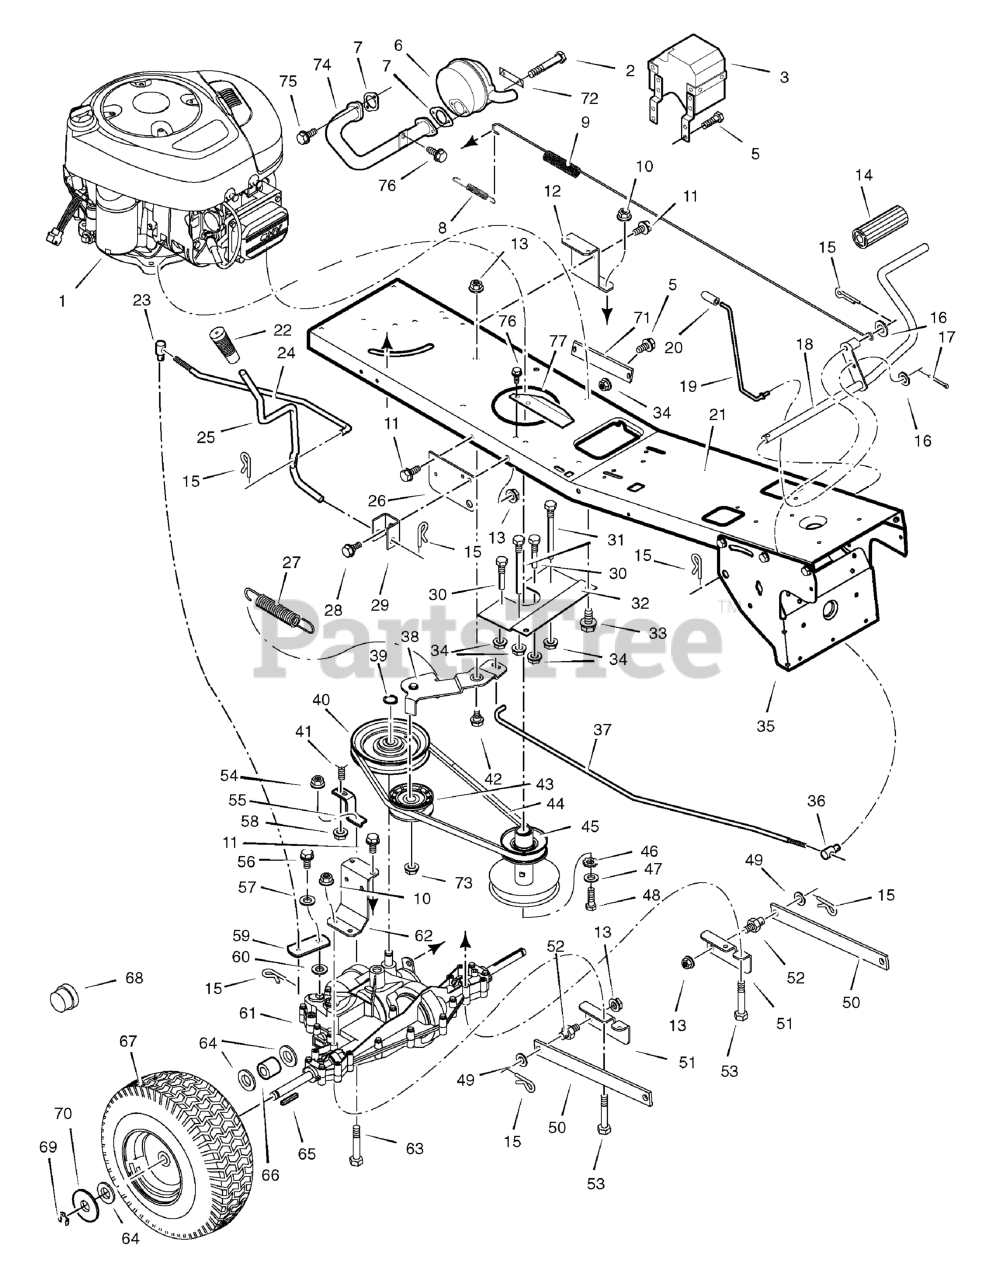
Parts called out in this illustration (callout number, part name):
1	Engine, Briggs & Stratton *
2	BOLT, Hex
3	SHIELD ASSEMBLY, Heat
7	GASKET, Exhaust
8	SPRING, Extension
9	SPRING, Extension
10	NUT
12	BRACKET, Left Transaxle
13	NUT, Flange
14	COVER, Pedal
15	PIN, Cotter
16	WASHER
17	PIN, Cotter
18	PEDAL ASSEMBLY
19	ROD, Parking Brake
20	GRIP, Parking Brake Rod
22	GRIP, Shift Lever
23	NUT, Adjusting
24	LINK, Shift
25	LEVER, Shift
26	BRACKET, Lift Pivot
27	SPRING, Extension
28	BOLT, Shoulder
29	BRACKET, Pivot
30	GUIDE, Belt Short
31	GUIDE, Belt Long
32	PLATE, Belt Guide
33	BOLT
34	NUT, Flange
35	BRACKET, Support
36	NUT, Adjusting
37	ROD, Clutch
38	CLUTCH ARM ASSEMBLY
39	RING, Retainer
40	PULLEY, Drive
41	BOLT, Carriage
42	BOLT, Shoulder
43	PULLEY, Idler
44	BELT, Motion Drive
45	PULLEY, Split Stack
46	WASHER, Star
48	BOLT, Hex
51	BRACKET, Rear Hanger
52	PIN, Threaded Shoulder
53	BOLT, Hex
54	NUT
55	BRACKET, Torque Reactor
57	WASHER, Shift Yoke
58	NUT
59	YOKE, Shift
61	Transaxle, Peerless **
62	BRACKET, Right Transaxle
63	BOLT, Hex
65	KEY, Square
66	SPACER, Rear Wheel
67	WHEEL, Rear, 15"
68	CAP, Hub
71	PLATE, Reinforcement
72	SCREW, Lock
73	NUT
74	TUBE, Exhaust
77	SHIELD, Heat
